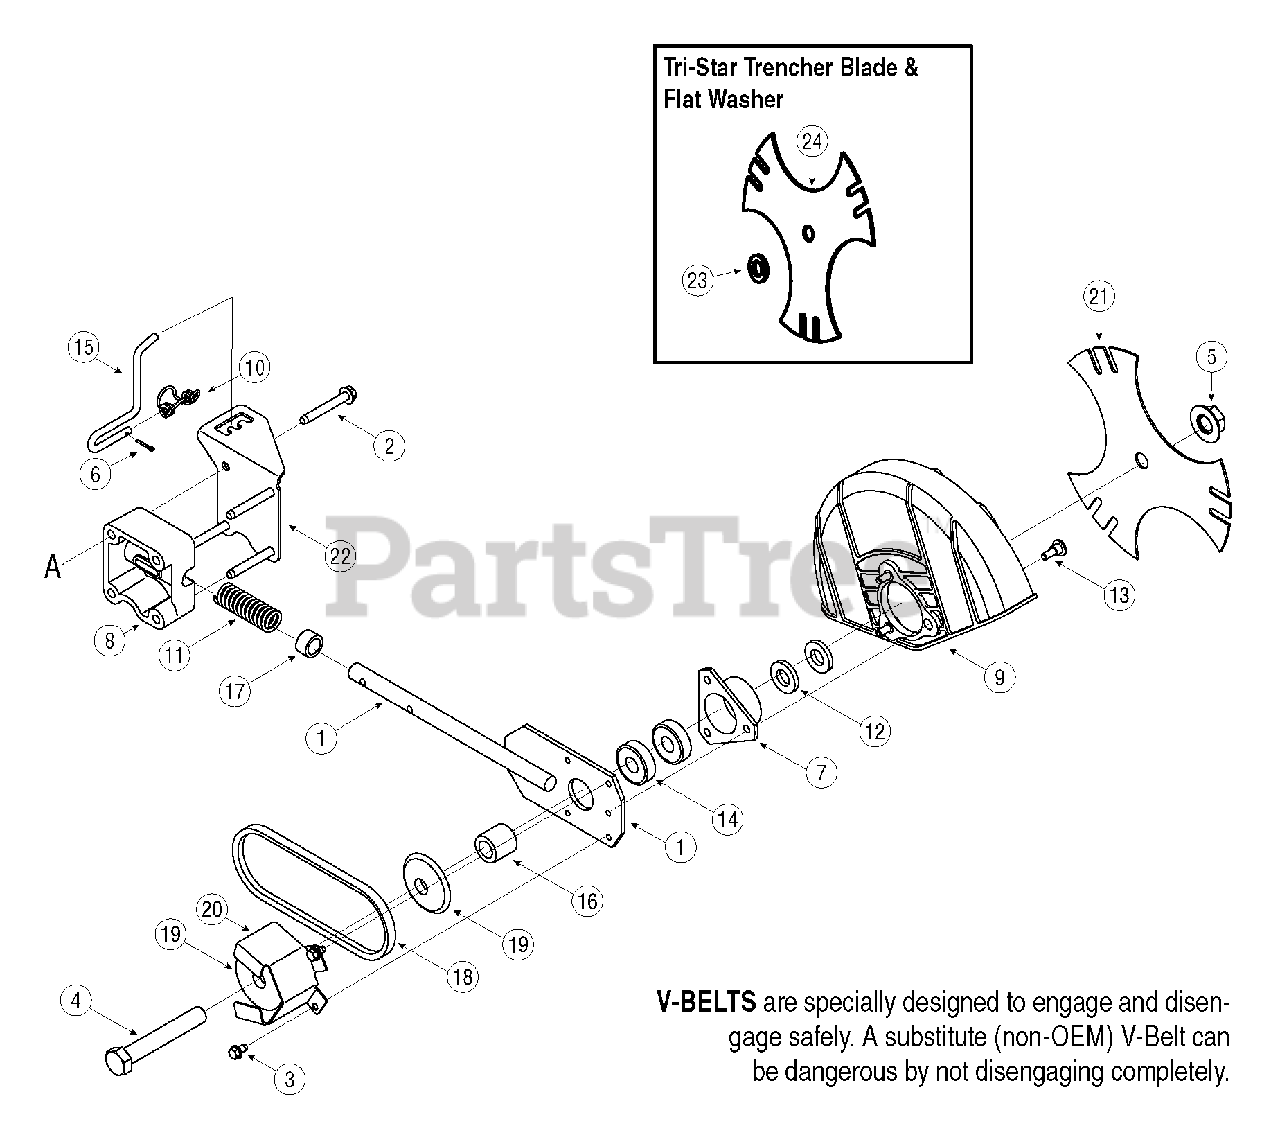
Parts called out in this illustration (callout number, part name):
1	Blade Plate Assembly
2	Hex Screw, 5/16-18
3	Self-tapping Screw, 1/4-20
4	Hex Screw, 5/8-18
5	Flange Nut, 5/8-18
6	Clevis Pin 3/32 x .625
7	Bearing Cup
8	Bearing Block
9	Blade Guard
10	Double Torsion Spring
11	Compression Spring
12	Flat Washer .635x1.24x.181
13	Shoulder Screw
14	Bearing, .625 ID x 1.57 OD
15	Blade Adjustment Rod
16	Spacer, .63 x 1.12 x 1.06
17	Spacer, .64 x.88 x .50
18	Belt
19	Sheave
23	Flat Washer
